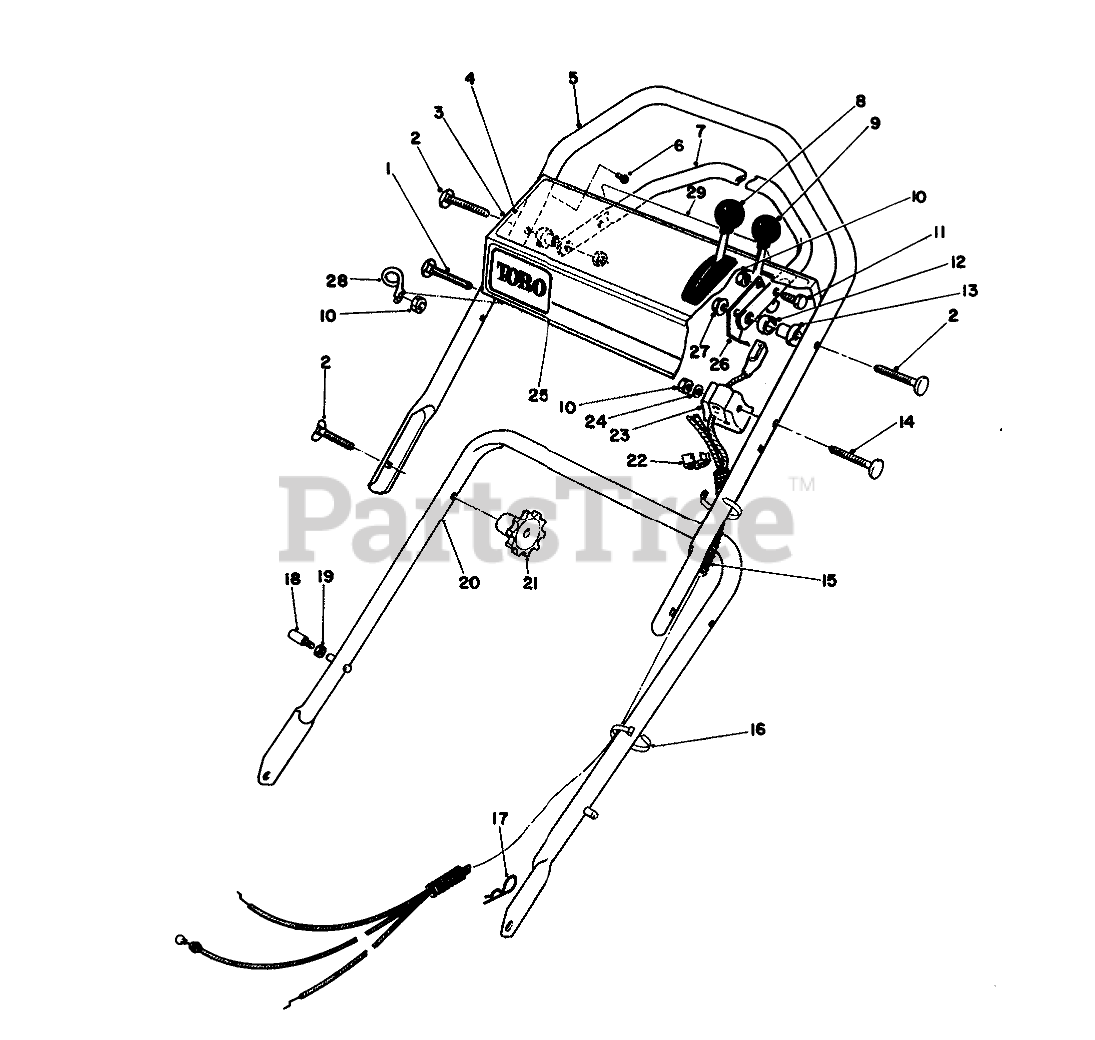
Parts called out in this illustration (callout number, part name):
1	HANDLE SCREW
2	5/16-18 X 2 HNDLE SCREW
3	Panel-Control (Incl. Ref. #4)
4	DECAL - INSTR (INT'L)
5	Handle-Upper
6	SCREW-HWHTF
7	Bar-Control
8	Control-Traction (Bend Type #3) Sheath Lg. 46")(Wire Lg. 2")
9	THROTTLE CONTROL - R&S
10	NUT-LOCK, NI
11	SCREW-HH
12	SPACER-NYLON
13	SPACER-SUPPORT
14	HANDLE SCREW
15	CONT. CABLE COVER
16	TIE-CABLE
17	PIN-COTTER, HAIR
18	CHOKE DECAL
19	NUT-LOCK, NI
20	LOWER HANDLE ASM
22	FITTING-RING
23	SUPPORT-CABLE
24	WASHER-FLAT
25	DECAL - TORO PANEL
26	LEVER-CONTROL
27	NUT-LOCK, NI
28	Guide
29	DECAL - PANEL, REAR
